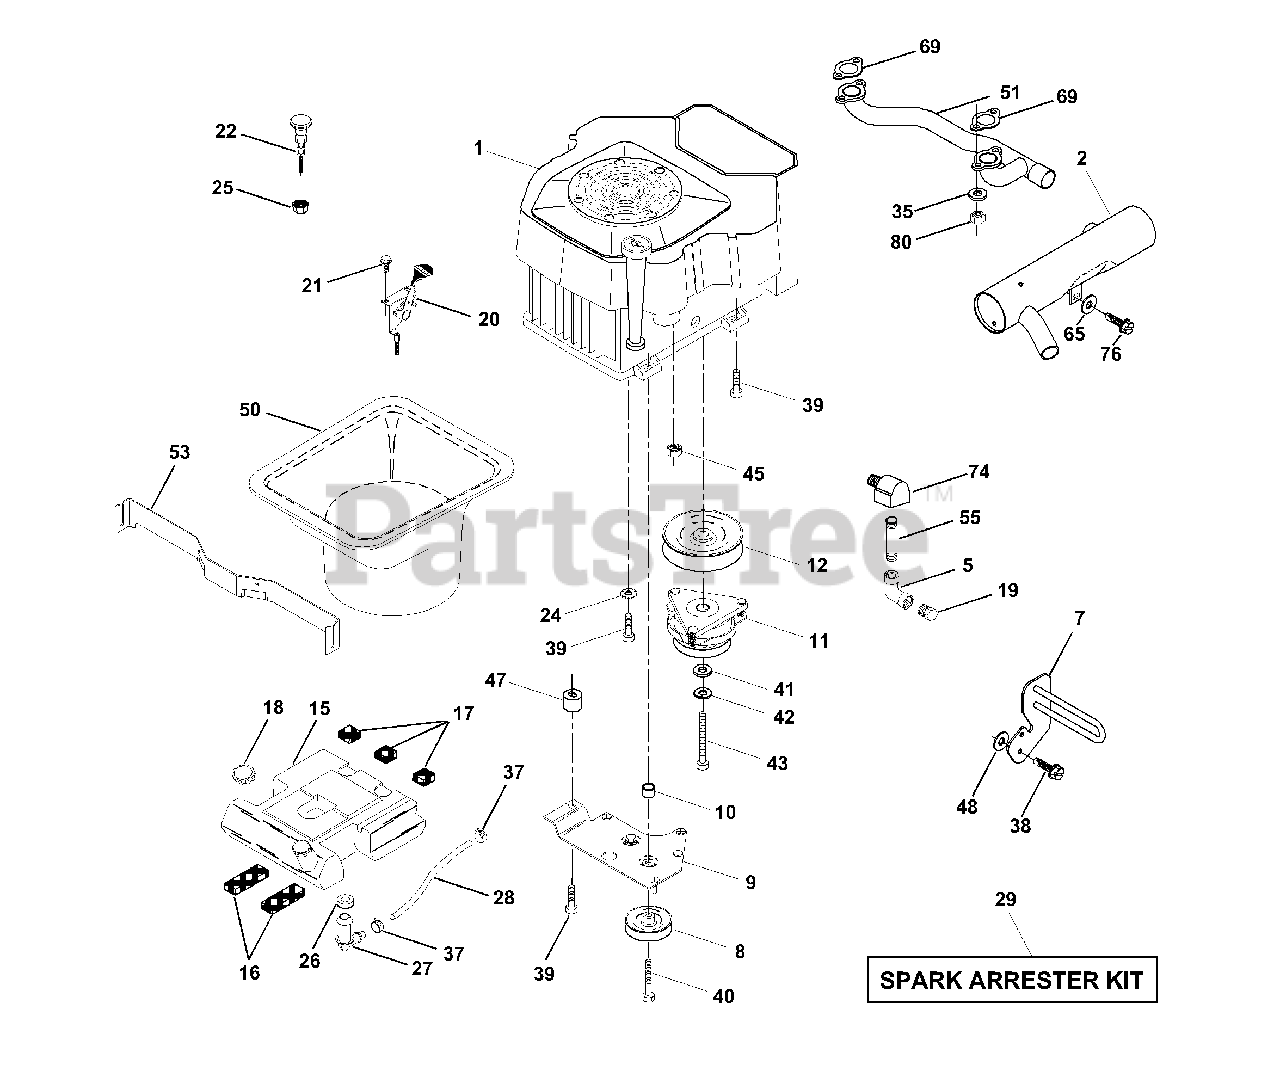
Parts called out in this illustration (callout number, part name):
2	Muffler Side
5	Elbow STD 90 Degree 3/8 - 18 NPT
7	Muffler Assembly Guard
8	Pulley V-Idler
9	Keeper Asm. Belt Engine VGT
10	Bushing
11	Clutch Electric
12	Pulley Engine VGT Elect Clutch
15	Tank Fuel Rear 3.50
16	Pad Spacer
17	Pad Spacer
18	Cap Asm Fuel W/Sym Vented
19	Plug Oil Drain
20	Control Throttle
21	Screw Hex Thd Cut 1/4 - 20 X 5/8
22	Control Choke
24	Washer Ext Tooth 3/8
25	Nut Keps 3/8-24 Unf
26	Bushing
27	Stem Tank Fuel
29	Spark Arrester Kit
35	Washer
37	Clamp Hose
38	Screw 3/8-16 x 1-1/4
39	Screw TT 3/8-16 x 2-1/4 UNC
40	Screw TT 3/8-16 x 4 UNC
41	Washer 1-1/2 OD X 15/32 ID X .250
42	Washer Lock 7/16
43	Bolt Hex 7/16-20 X 4-1/4 Ga 5
45	Nut Keps Hex 1/4-20
47	Spacer Engine CV22 Round PM
48	Washer 13/32 x 1-1/4 x 7 Ga.
50	Duct Air Intake
51	Manifold VGT
53	Rod Support Hood Duct
55	Nipple, Pipe 4-1/2
65	Washer 13/32 x 1 x 14 Ga.
69	Gasket
74	Elbow Street Brass
76	Screw Hexwsh Thdrol 3/8-16 x 3/4
80	Nut Flange M8-1.25
